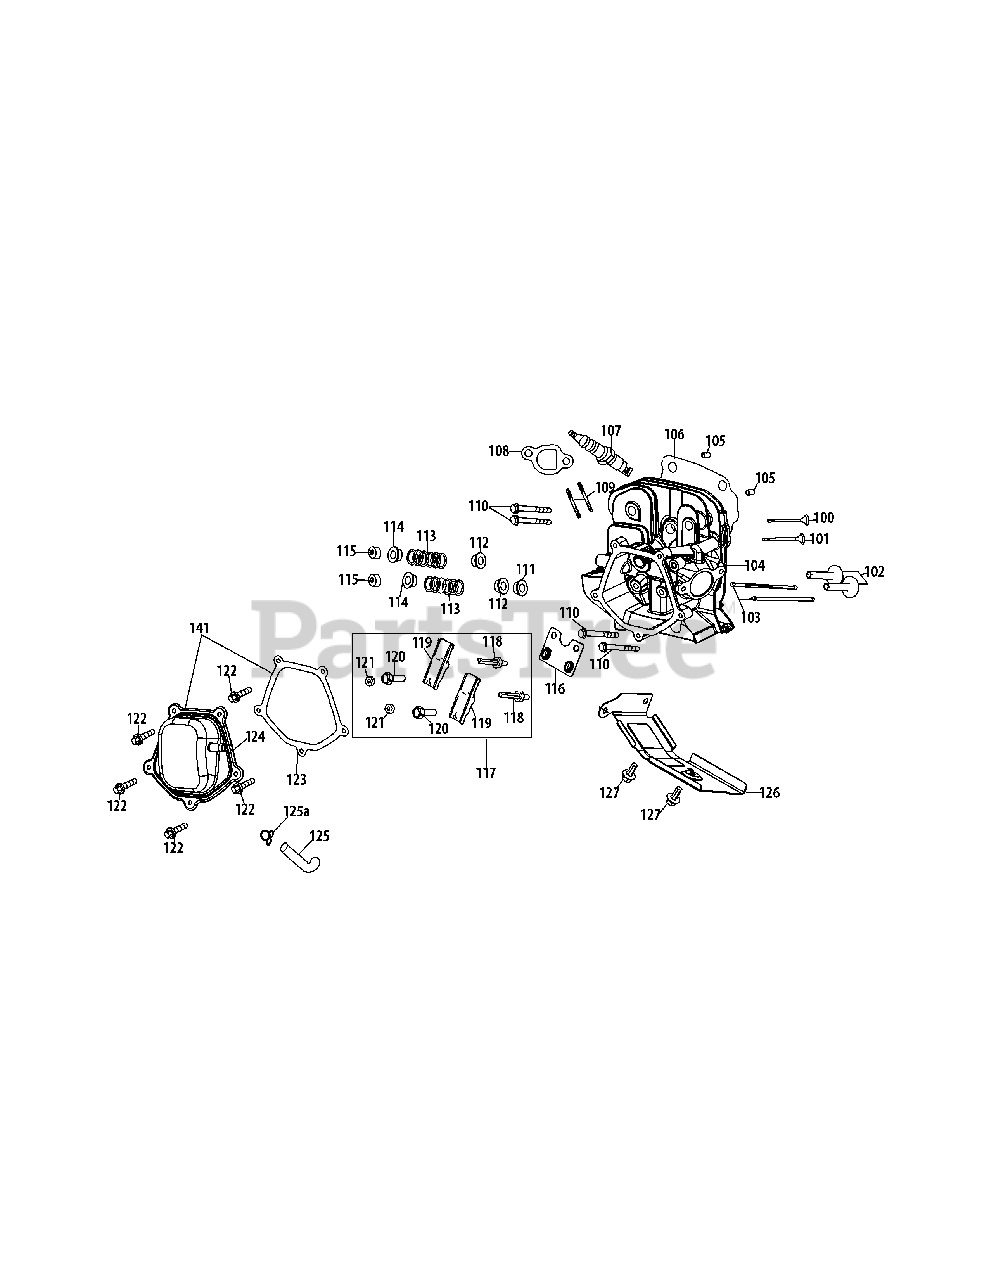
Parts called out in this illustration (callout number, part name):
102	Tappet
103	Push Rod Kit
104	Cylinder Head Kit
105	Dowel Pin 12×20
106	Gasket, Cylinder Head
107	Spark Plug
108	Exhaust Pipe Gasket
109	Stud M8×48.5
109	Muffler Stud Assembly
110	Bolt M10×1.25×80
111	Intake Valve Seal
112	Valve Spring Retainer
113	Valve Spring
114	Retainer, Ex. Valve Spring
115	Adjuster, Ex. Valve
116	Push Rod Guide
117	Rocker Arm Assembly
118	Bolt, Pivot
119	Rocker Arm
120	Adjusting Nut ,Valve
121	Nut, Pivot Locking
122	Valve Cover Bolt
123	Valve Cover Gasket
124	Valve Cover
125	Breather Hose
126	Cylinder Baffle
127	Bolt M6×12
141	Valve Cover Kit
